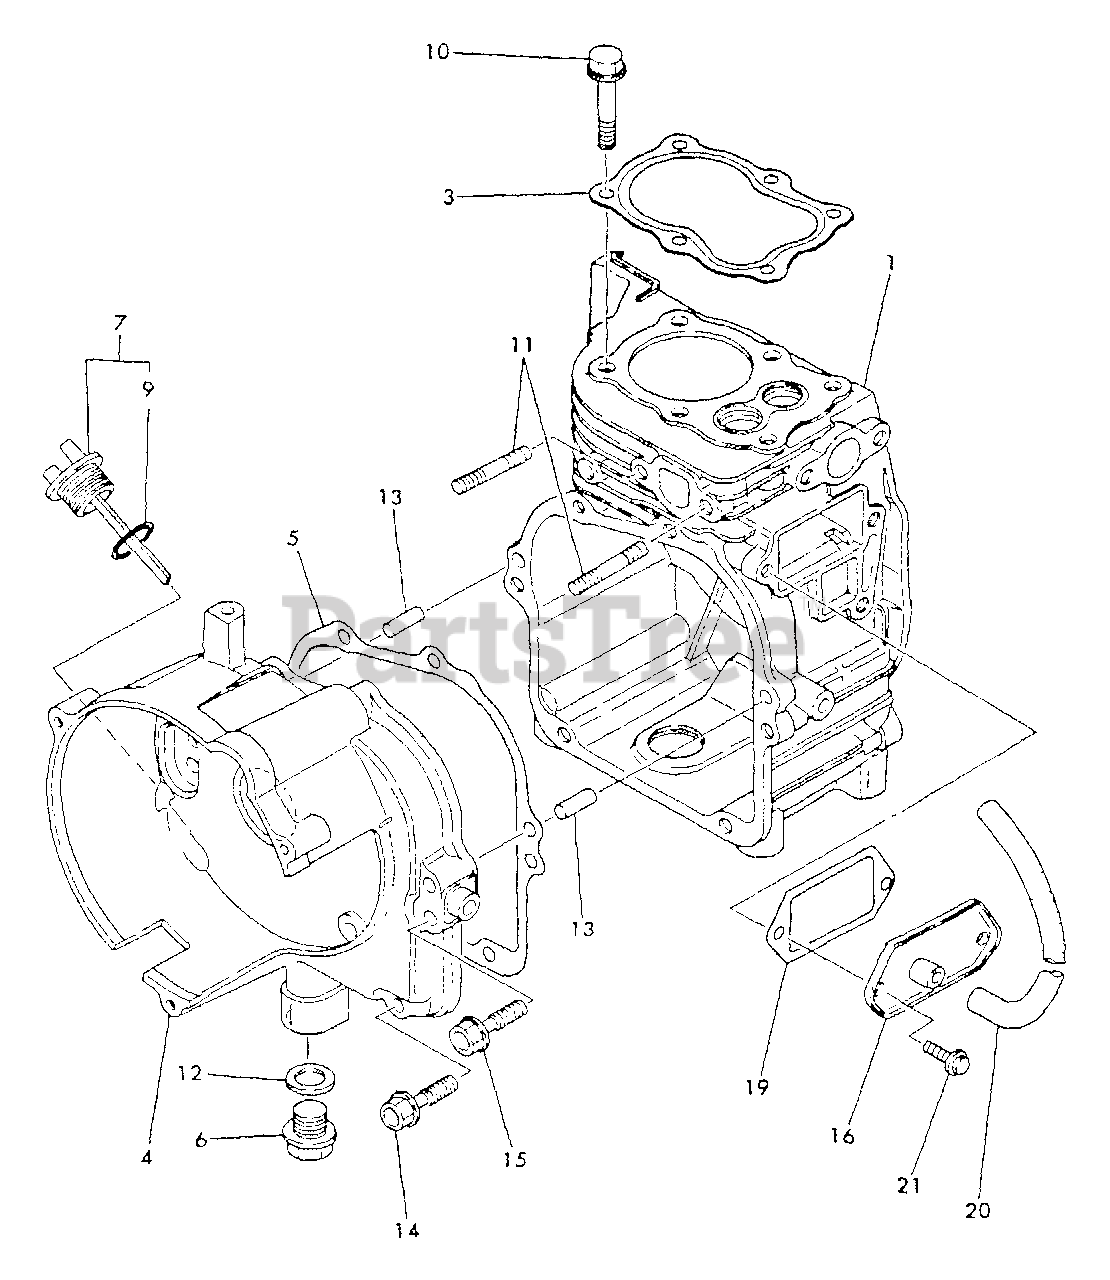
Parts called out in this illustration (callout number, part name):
1	CYLINDER BLOCK SET
3	GASKET, CYLINDER
4	COVER, CRANKCASE
5	GASKET, CRANKCASE
6	PLUG, DRAIN
7	CAP ASSY
9	O-RING - 18
10	BOLT - 6X35
11	BOLT - 6X16
12	GASKET
13	PIN - 6X16
14	BOLT - 6X25
15	BOLT - 6X30
16	BREATHER
19	GASKET, TAPPET
20	PIPE - BREATHER
21	BOLT - 6X8 -- PLATED
